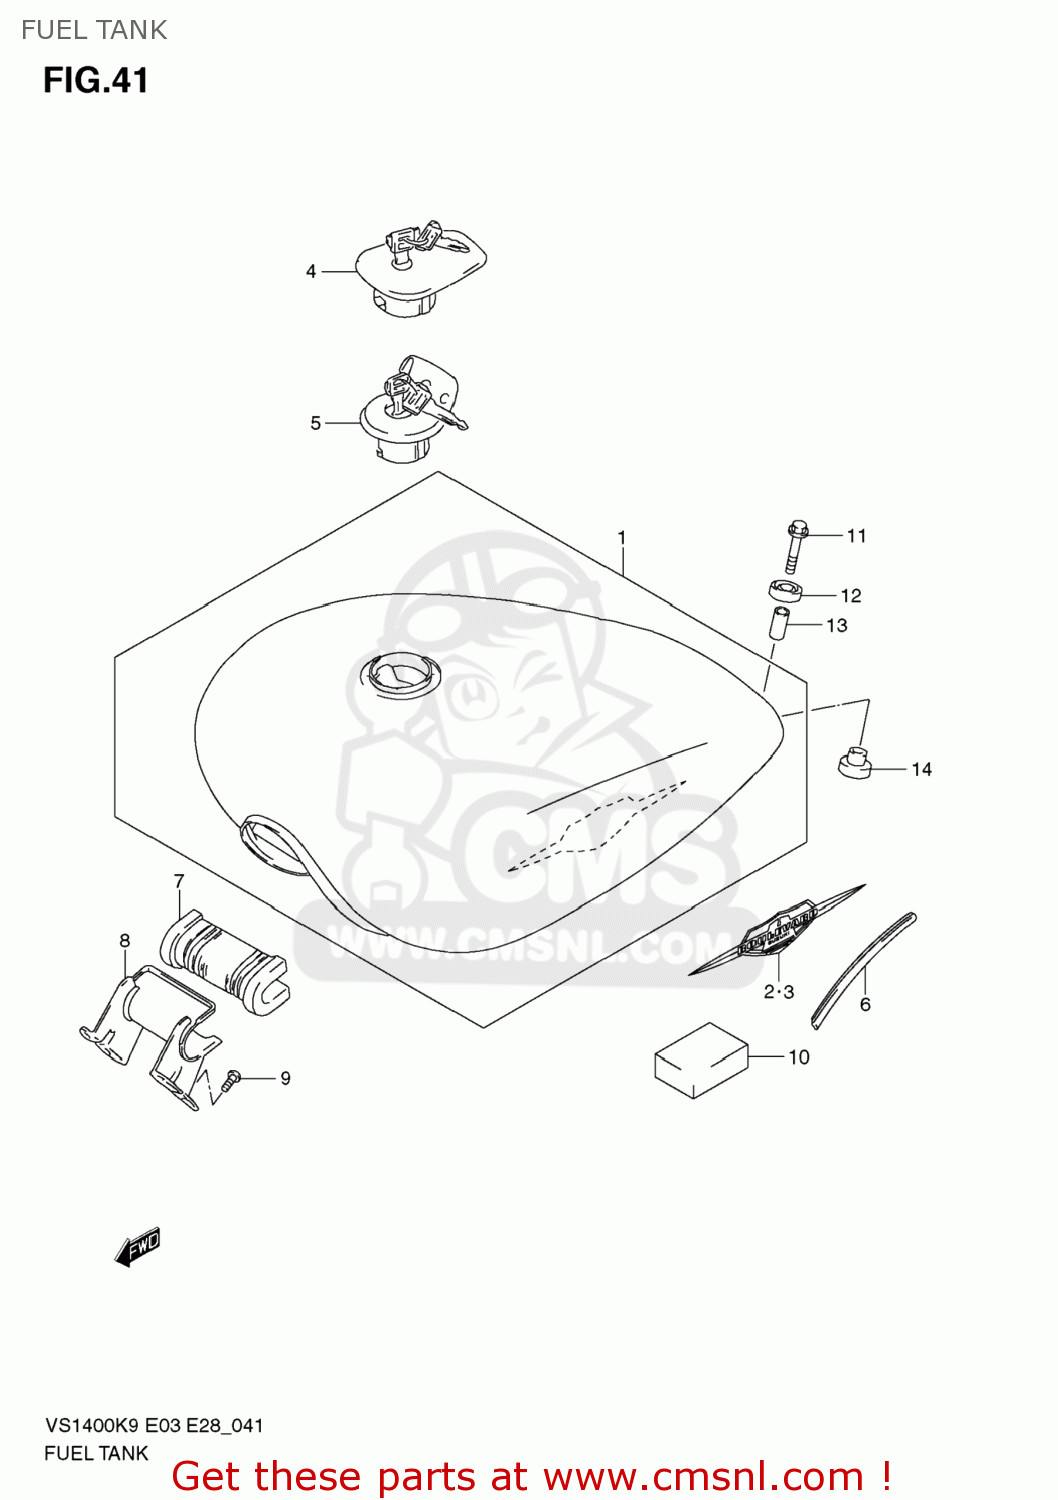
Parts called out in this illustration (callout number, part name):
1	TANK ASSY,FUEL(GRAY)
2	EMBLEM,FUEL TANK,R
3	EMBLEM,FUEL TANK,L
4	CAP SET,FUEL TANK
5	CAP SET,FUEL TANK
6	MOLDING
7	CUSHION,FUEL TANK FR
8	BRACKET,FUEL TANK FR
9	SCREW
10	CUSHION
11	BOLT
12	CUSHION
13	SPACER(6.5X9X22.5)
14	CUSHION
